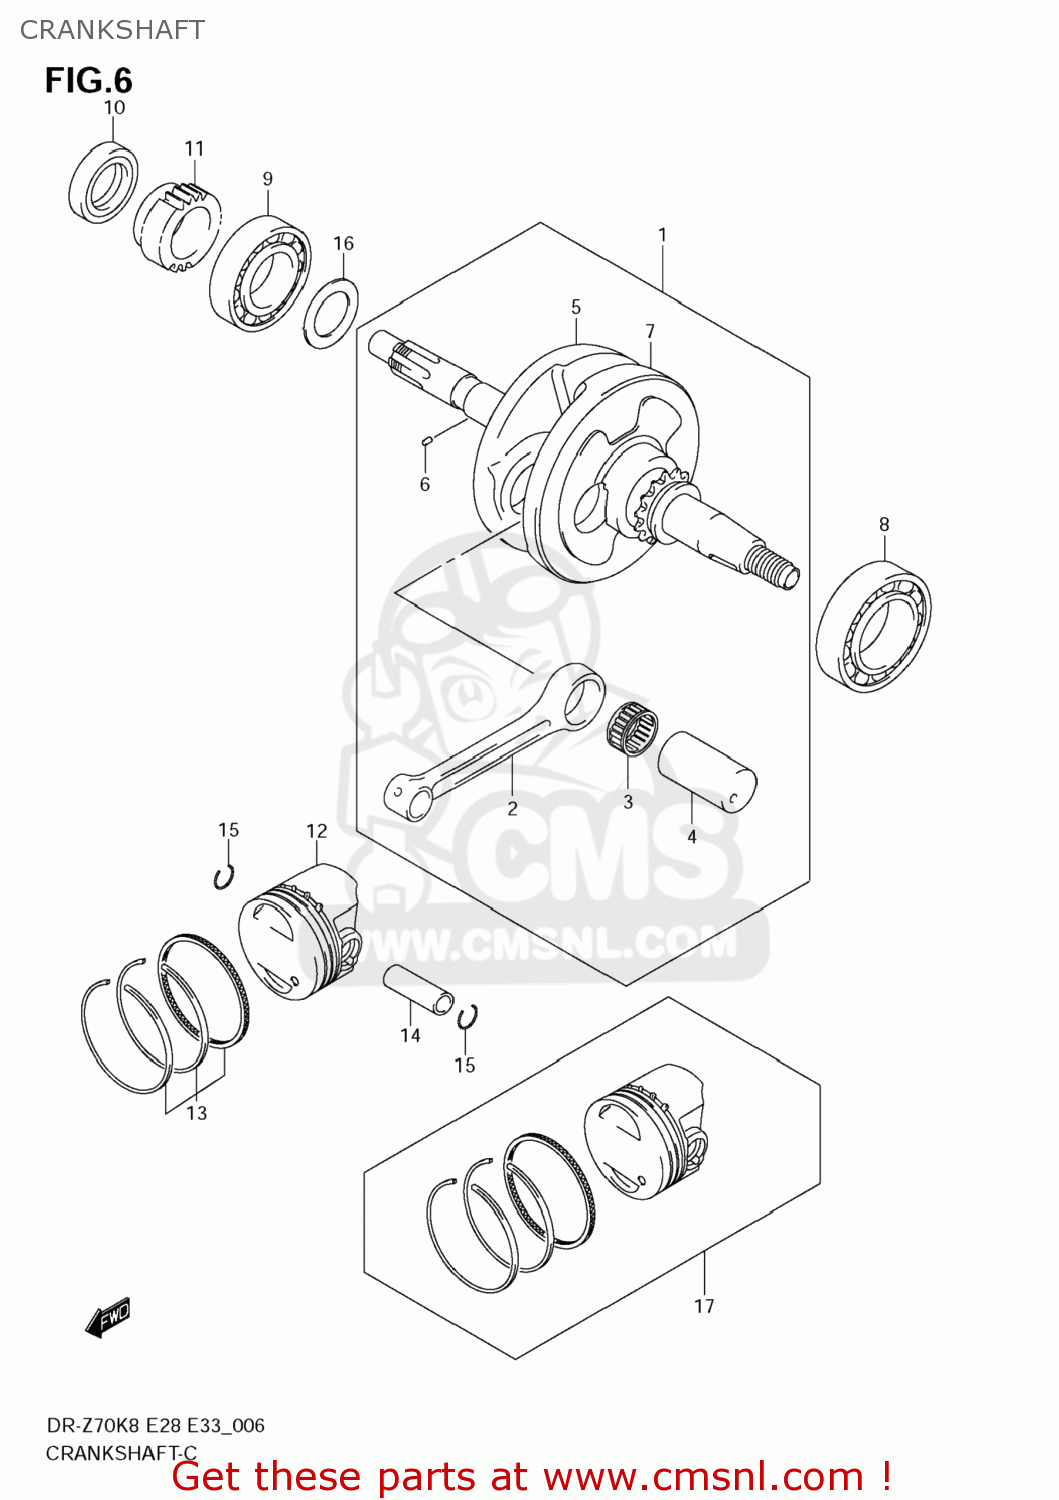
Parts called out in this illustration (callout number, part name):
1	CRANKSHAFT ASSY
2	CONNECTING ROD
3	PIN,CRANK
4	BEARING(22X28X14)
5	CRANKSHAFT,R
6	PIN
7	CRANKSHAFT,L
8	BEARING(35X62X14)
9	BEARING(20X52X15)
10	SEAL,OIL(20X32X7)
11	GEAR,OIL PUMP DRIVE
12	PISTON
13	RING SET,PISTON
14	PIN,PISTON
15	RING,SNAP
16	SHIM(20X30X1)
17	PISTON SET(OS:0.5)
